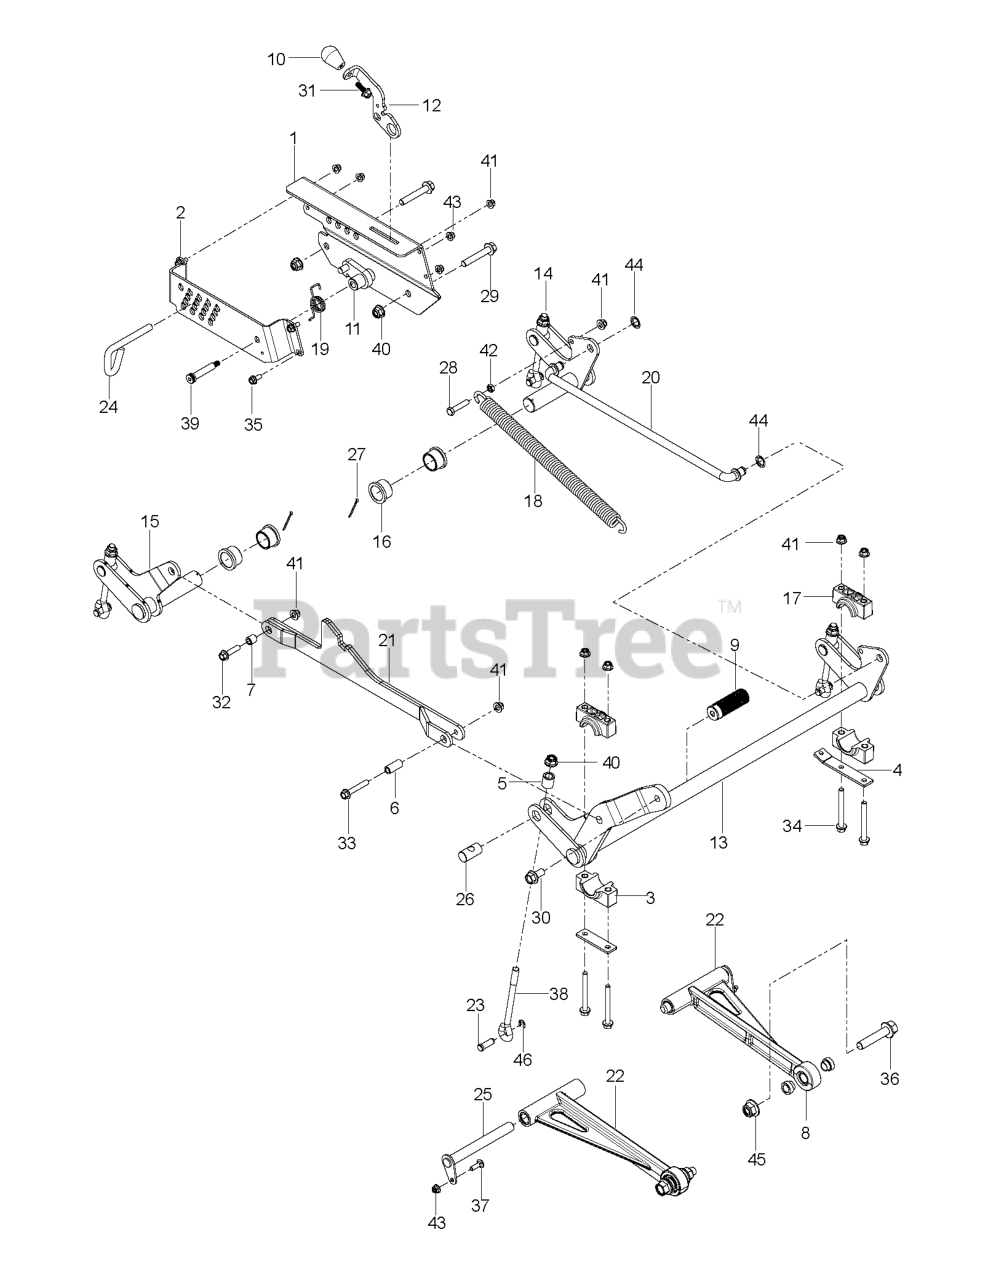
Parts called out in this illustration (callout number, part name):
1	PLATE HEIGHT SNAPPER RED X672
2	PLATE HEIGHT SNAPPER RED X672
3	PLATE, PILLOW BLACK
4	PLATE, SPRING ANCHOR
5	SPACER, EYEBOLT
6	SPACER, FRONT LIFT STRAP
7	SPACER, REAR LIFT STRAP
8	SPACER, STRUT
9	PEDAL, DECK HEIGHT
10	KNOB - SHIFT
11	LATCH, TRANSPORT WLDMT
12	LEVER, TRANSPORT RELEASE
13	SHAFT DECK LIFT FT
14	SHAFT, LIFT LEFT REAR
15	SHAFT, LIFT RIGHT REAR
16	BUSHING, FLANGE 1.25 X 1.0
17	BLOCK, PILLOW
18	SPRING, EXTENSION
19	SPRING, TORSION
20	ROD, LIFT
21	WELDMT, DECK STRAP
22	ASSEMBLY, STRUT
23	PIN, 7/16 CLEVIS
24	PIN, HEIGHT
25	PIN, STRUT
26	PIN, TRUNION, EYEBOLT
27	COTTER PIN 1/8 X 2
28	HCS 3/8-16 X 1 3/4 GR5
29	HFFS 1/2-13 X 3 GD 5 ZD
30	HHFS 1/2-13 X 1 GR5 ZD
31	HHFS 3/8-16 X 1 GRD 5 ZD
32	HHFS 3/8-16 X 1.50 GR5 ZD
33	HHFS 3/8-16 X 2-1/4 GR 5 ZD
34	HHFS 3/8-16 X 3.5 GD 5 ZD
35	HHFS 5/16-18 X 3/4
36	HHFS 5/8-11 X 3.0 GD 8 ZD
37	RHSNB 5/16C X 1
38	EYEBOLT, DECK LIFT
39	BOLT, SHOULDER, 1/2 X 2.25
40	NUT, 1/2-13 HEX FLG NYLOC ZD
41	NUT 3/8-16 HEX FLG NYLOC ZD
42	NUT 3/8-16 HEX JAM
43	5/16-18 NYLOC FLANGE NUT
44	NUT 5/8 PUSH
45	NUT 5/8-11 FLG NYLOC ZD
46	RING, E, 7/16
